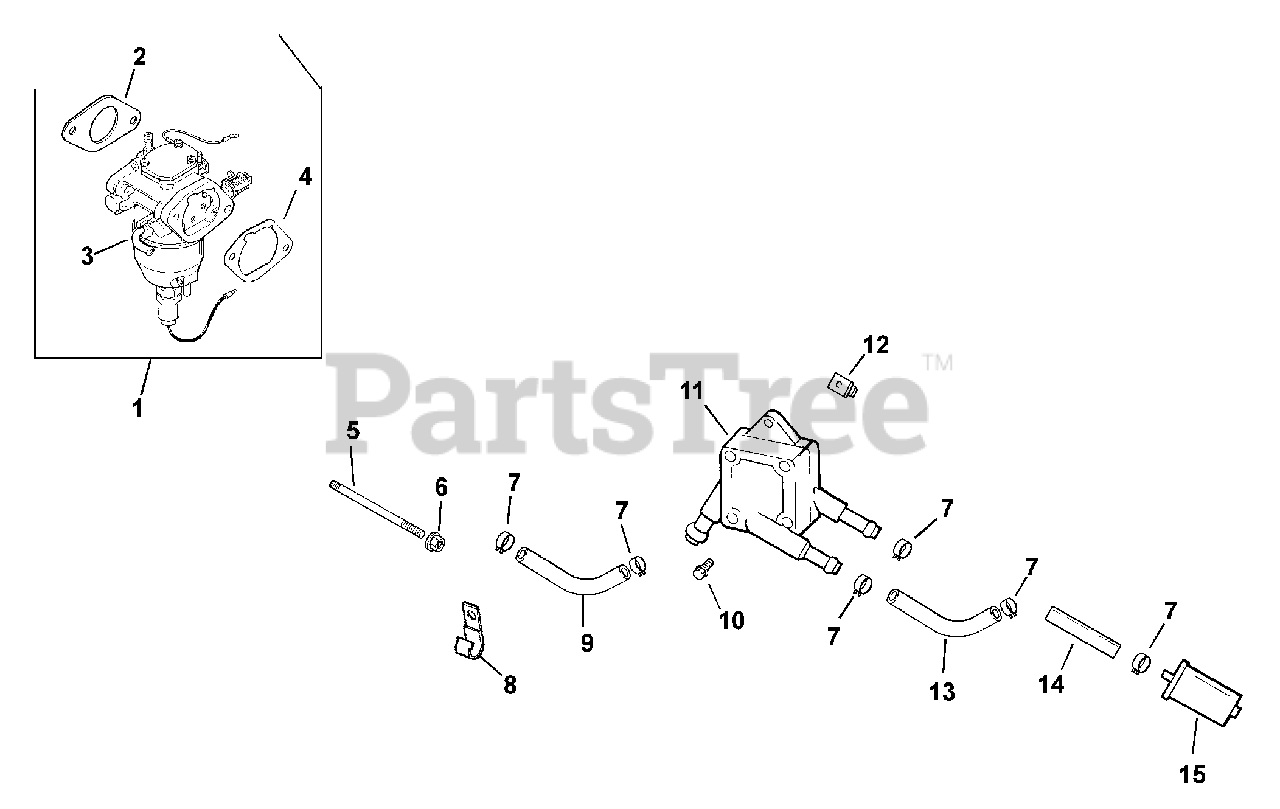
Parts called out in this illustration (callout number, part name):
1	KIT, CARBURETOR W/ GASKETS
2	GASKET, CARBURETOR
3	Carburetor assembly
4	GASKET, AIR CLEANER BASE
5	STUD,M6X1.0X116
6	NUT, FLG M6X1.0
7	CLAMP, HOSE (KM)-USE 25 237 31-S
8	CLIP, CABLE
9	LINE, FLEXIBLE FUEL 10.92"-USE 24 353 12
10	SCREW, TAP M6X1.7X18
11	PUMP, FUEL
12	NUT, PLASTIC (KM)-USE 25 100 37-S
13	LINE, FLEXIBLE FUEL - DISCONTINUED
14	LINE FLEXBLE FUEL (3.5" x.25") -USE 25 1
